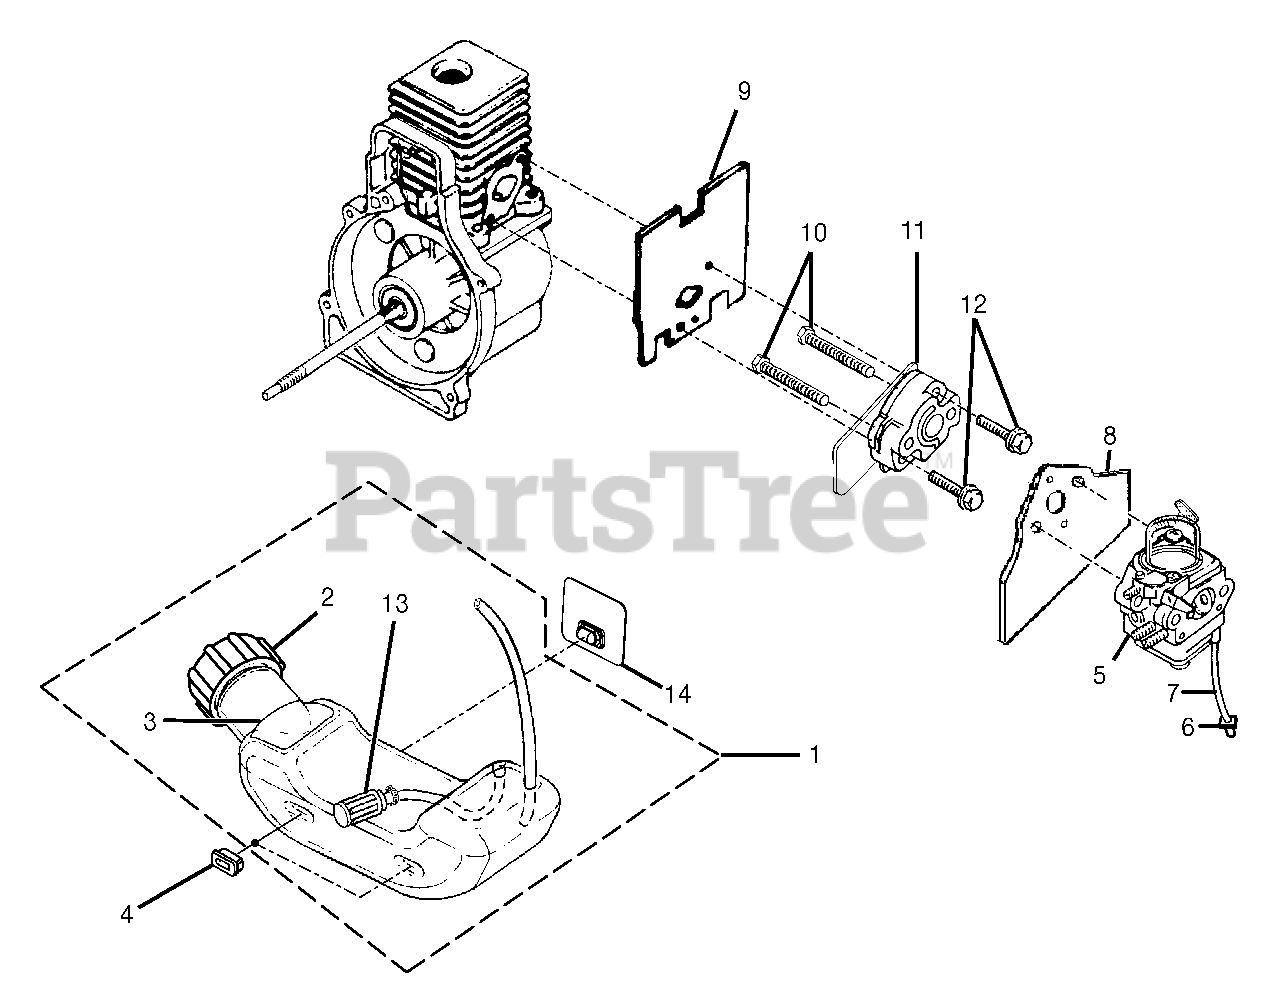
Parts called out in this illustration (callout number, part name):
1	FUEL TANK KIT
2	FUEL TANK CAP
3	HEAT SHIELD
4	RUBBER BUMPER
5	CARBURETOR
6	INLINE FUEL FITTING
7	RUBBER TUBBING (3 in)
8	CARBURETOR GASKET
9	HEAT DAM GASKET
10	SCREW (10-24 x 1 in HEX HD )
12	SCREW (10-24 x 1110 in PAN HD)
13	FUEL FILTER KIT
14	RUBBER BUMPER (LARGE)
